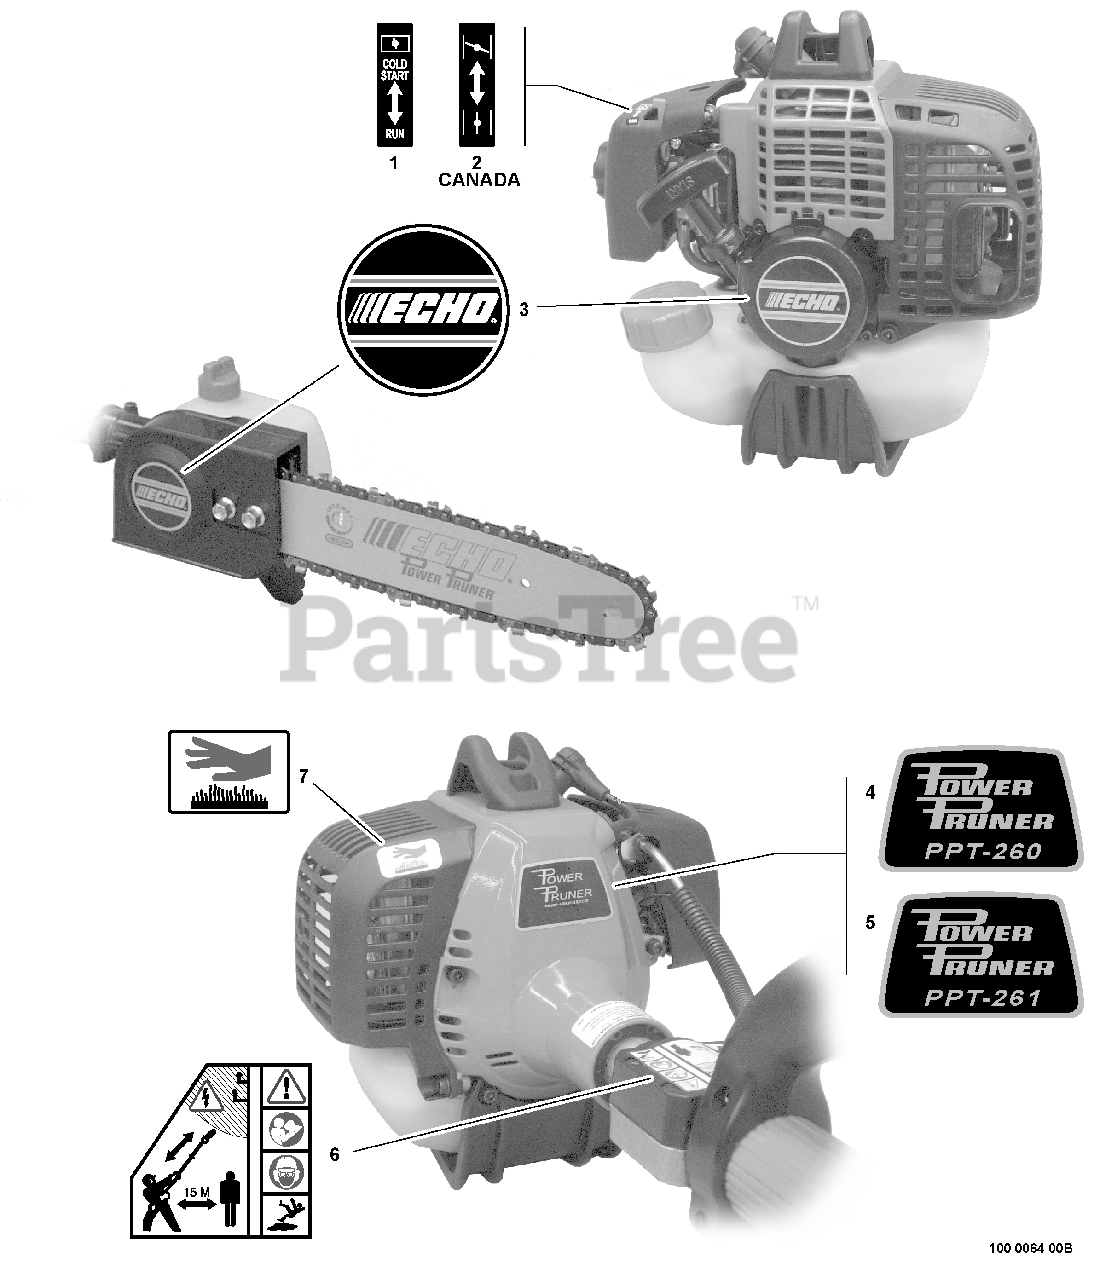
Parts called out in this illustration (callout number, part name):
1	LABEL - CHOKE
2	LABEL - CHOKE
3	LABEL - ECHO
4	LABEL - MODEL PPT-260
5	LABEL - MODEL PPT-261
6	LABEL - CAUTION
7	LABEL - HOT SURFACE
